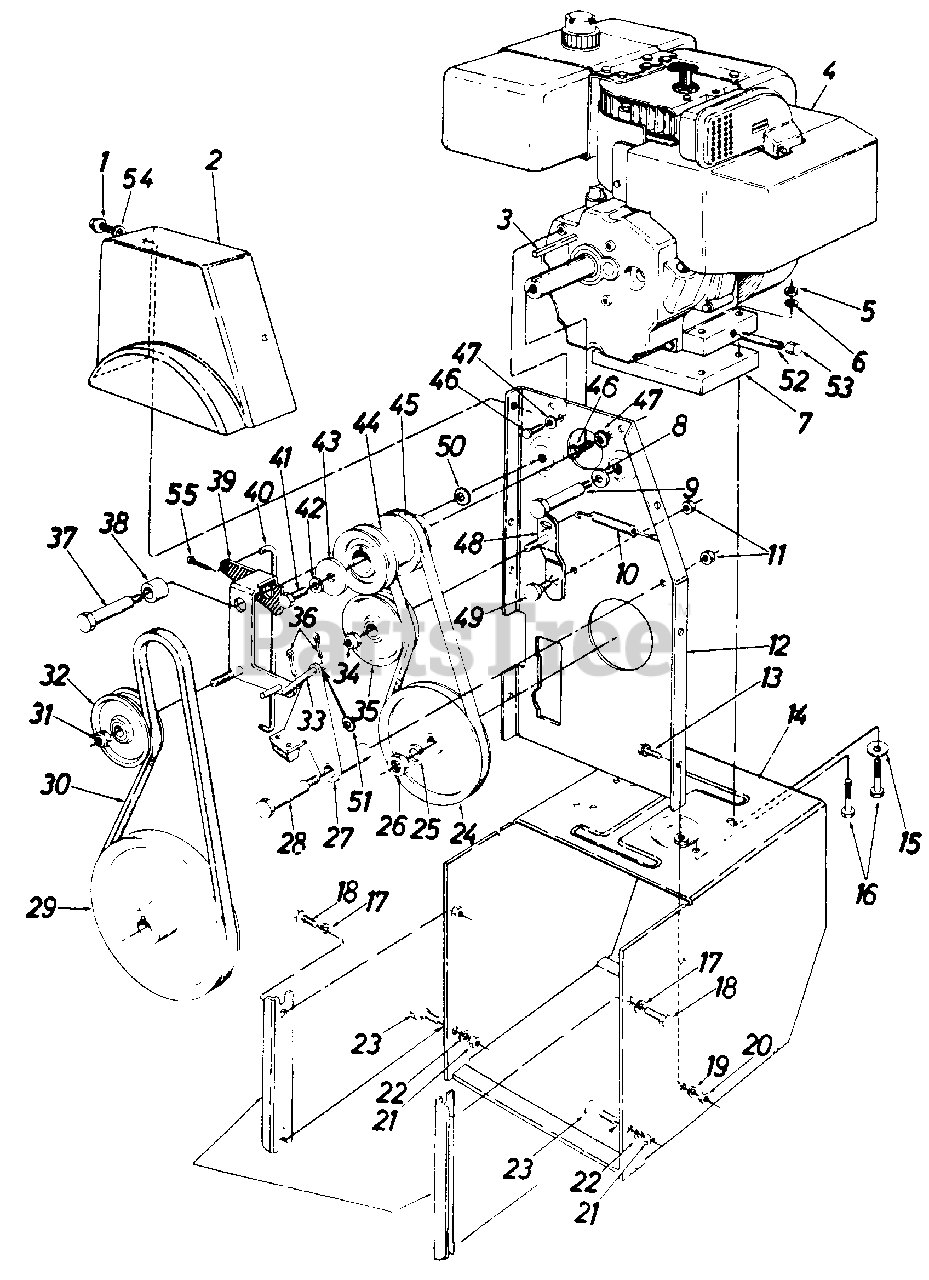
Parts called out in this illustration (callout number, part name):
1	Hex AB-Tap Scr. 5/16 x .75" Lg.
2	Belt Cover
3	Sq. Key 1/4" X 1.50" Lg.
4	Engine
5	Hex Nut 5/16-18 Thd.
6	L-Wash. 5/16" I.D.
7	Engine Spacer Ass'y.
8	Bell-Wash. .40 I.D. x .88 O.D.
9	Shld. Bolt .498" Dia. x 3.00" Lg.
10	Ext. Spring .38 O.D. x 3.18" Lg.
11	Hex Cent. L-Nut 3/8-16 Thd.
12	Engine Brkt. Ass'y.
13	Hex Sems Scr. 5/16-18 x .75" Lg
14	Frame Ass'y.
15	Fl-Wash. .345 I.D. x .75 O.D. x .060
16	Hex Bolt 5/16-18 x 2.50" Lg.
17	L-Wash. 3/8" I.D. H.D.
18	Pilot Scr. 3/8-16 x .88" Lg.
19	L-Wash. 5/16" I.D.
20	Hex Nut 5/16-18 Thd.
21	Hex Nut 3/8-16 Thd.
22	L-Wash. 3/8" I.D. H.D.
23	Shld. Bolt .498" Dia. x .340" Lg.
24	V-Pulley .628 I.D. x 7.50 O.D.
25	L-Wash. for 5/8" I.D.
26	Hex Ins. Jam L-Nut 5/8-18 Thd.
27	Brake Brkt. Ass'y.
28	Shld. Bolt .498" Dia. x 2.00" Lg.
29	V-Pulley .875 I.D. x 10.12 O.D.
30	"V"-Belt
31	Hex Ins. Jam L-Nut 3/8-24 Thd.
32	Fl-Idler w/Flanges 3.0 O.D.
33	Brake Linkage Ass'y.
34	Hex Ins. Jam L-Nut 3/8-24 Thd.
35	3.0" O.D. Fl-Idler w/Flanges
36	Int. Cot. Pin 3/32" Dia.
37	Shld. Bolt .625" Dia. x 2.750" Lg.
38	Spacer .75 O.D. x 1.00" Lg.
41	Hex Bolt 3/8-24 x 1.25" Lg.
42	L-Wash. 3/8" I.D. H.D.
43	Fl-Wash.
44	Engine Pulley-Double Groove
45	"V"-Belt
46	Hex Bolt 5/16-24 x .62" Lg.
47	Bell-Wash. .345 I.D. x .88 O.D. x .060
48	Drive Idler Brkt. Ass'y.
49	Shld. Bolt-.625" Dia. x .170" Lg.
50	Bell-Wash. .40 I.D. x 1.12 O.D.
51	Fl-Wash. .385" I.D. x .620" O.D.
52	Pipe Nipple-1/4" Pipe Thd. x 3.5" Lg.
53	Hex Hd. Cap 1/4-18 Pipe Thd.
54	Fl-Wash. .340 I.D. x .62 O.D. x .62
55	Int. Cot. Pin 5/16" Dia.
